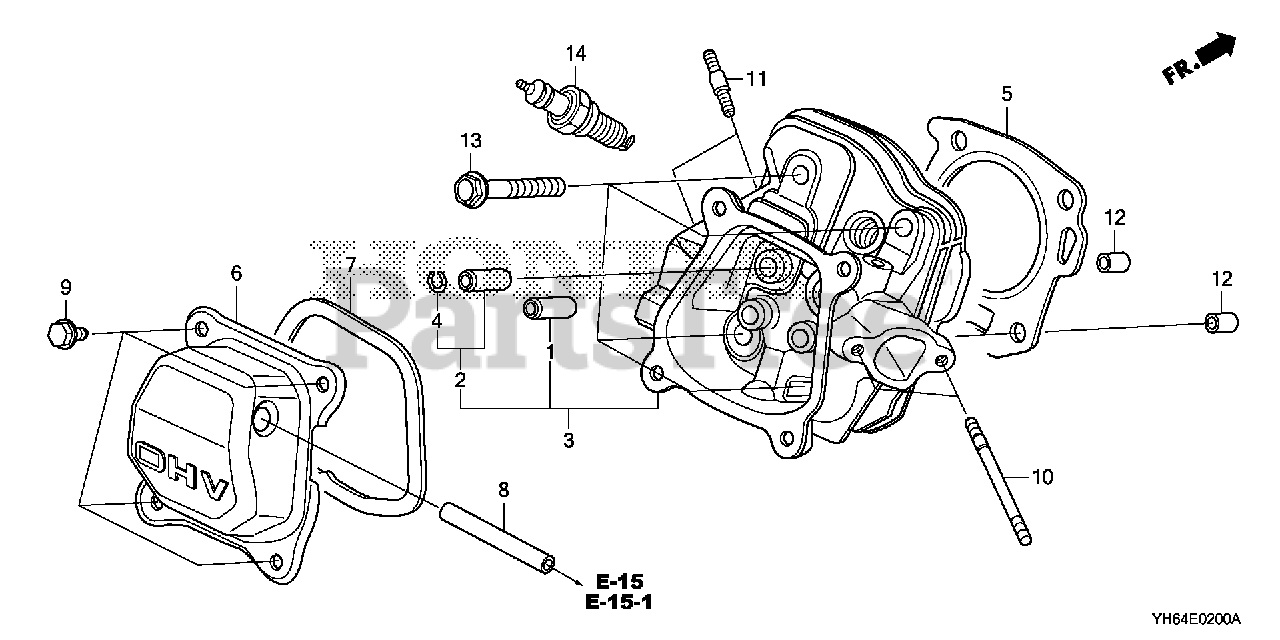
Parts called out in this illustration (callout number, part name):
3	CYLINDER HEAD
5	GASKET, CYLINDER HEAD
6	COVER, HEAD
7	GASKET, HEAD COVER
8	TUBE, BREATHER
9	BOLT, FLANGE (6X12) (CT200)
10	BOLT, STUD (6X114)
11	BOLT, STUD (8X32)
12	PIN A, DOWEL (10X16)
13	BOLT, FLANGE (8X55)
14	SPARK PLUG (BPR6ES) (NGK)
14	SPARK PLUG (W20EPR-U) (DENSO)
